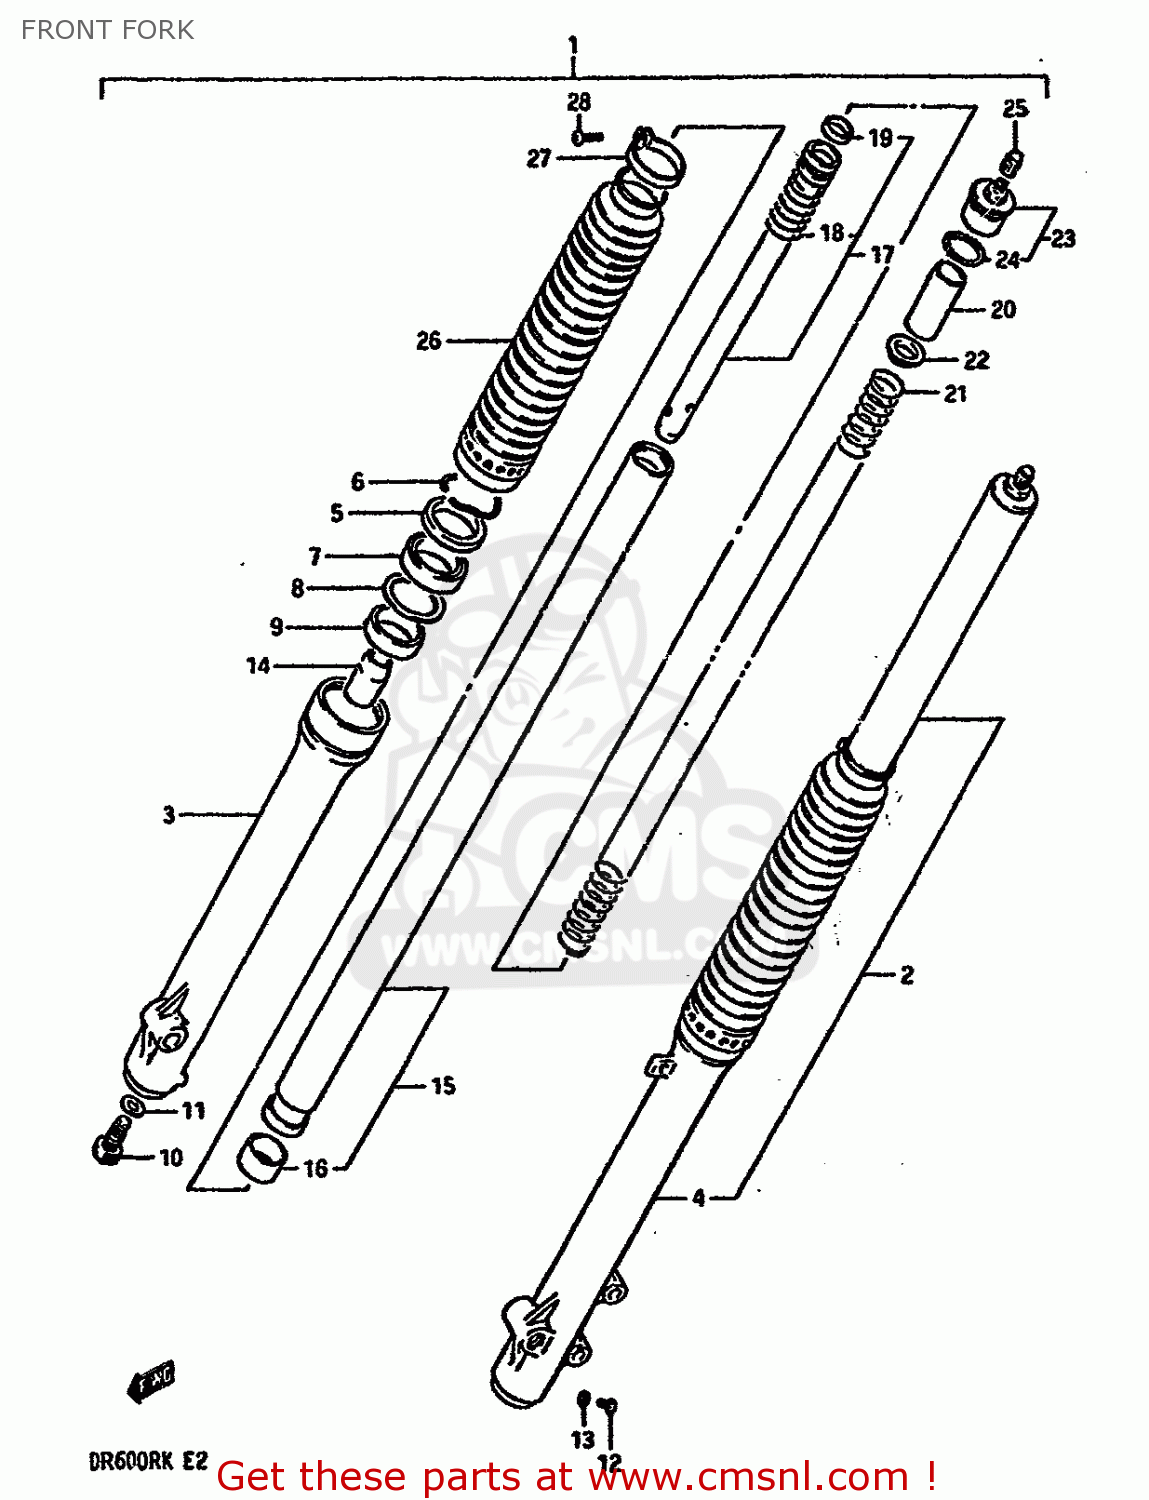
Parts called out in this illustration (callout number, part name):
1	DAMPER ASSEMBLY,FRONT FORK,RIGHT
2	DAMPER ASSEMBLY,FRONT FORK,LEFT
3	TUBE,FORK,OUTER,RIGHT
4	TUBE,FORK,LEFT,OUTER
5	SEAL,DUST
6	RING,OIL SEAL STOPPER
7	SEAL,OIL
8	WASHER,FORK OIL SEAL
9	METAL,FR FORK SLIDE
10	BOLT,CYLINDER
11	GASKET,CYLINDER (NAS)
12	SCREW 4X6
13	GASKET,DRAIN,PLUG (NAS)
14	PIECE,FRONT FORK OIL LOCK
15	TUBE,FORK,INNER
16	METAL,SLIDE FR FORK
17	CYLINDER,FRONT FORK
18	SPRING,REBOUND
19	RING,FRONT FORK PISTON
20	SPACER,FRONT FORK SPRING
21	SPRING,FRONT FORK
22	GUIDE,FR FORK SPRING
23	CAP,FORK INNER TUBE
24	O RING
25	CAP
26	BOOT
27	BAND,BOOT
28	SCREW 4X10
